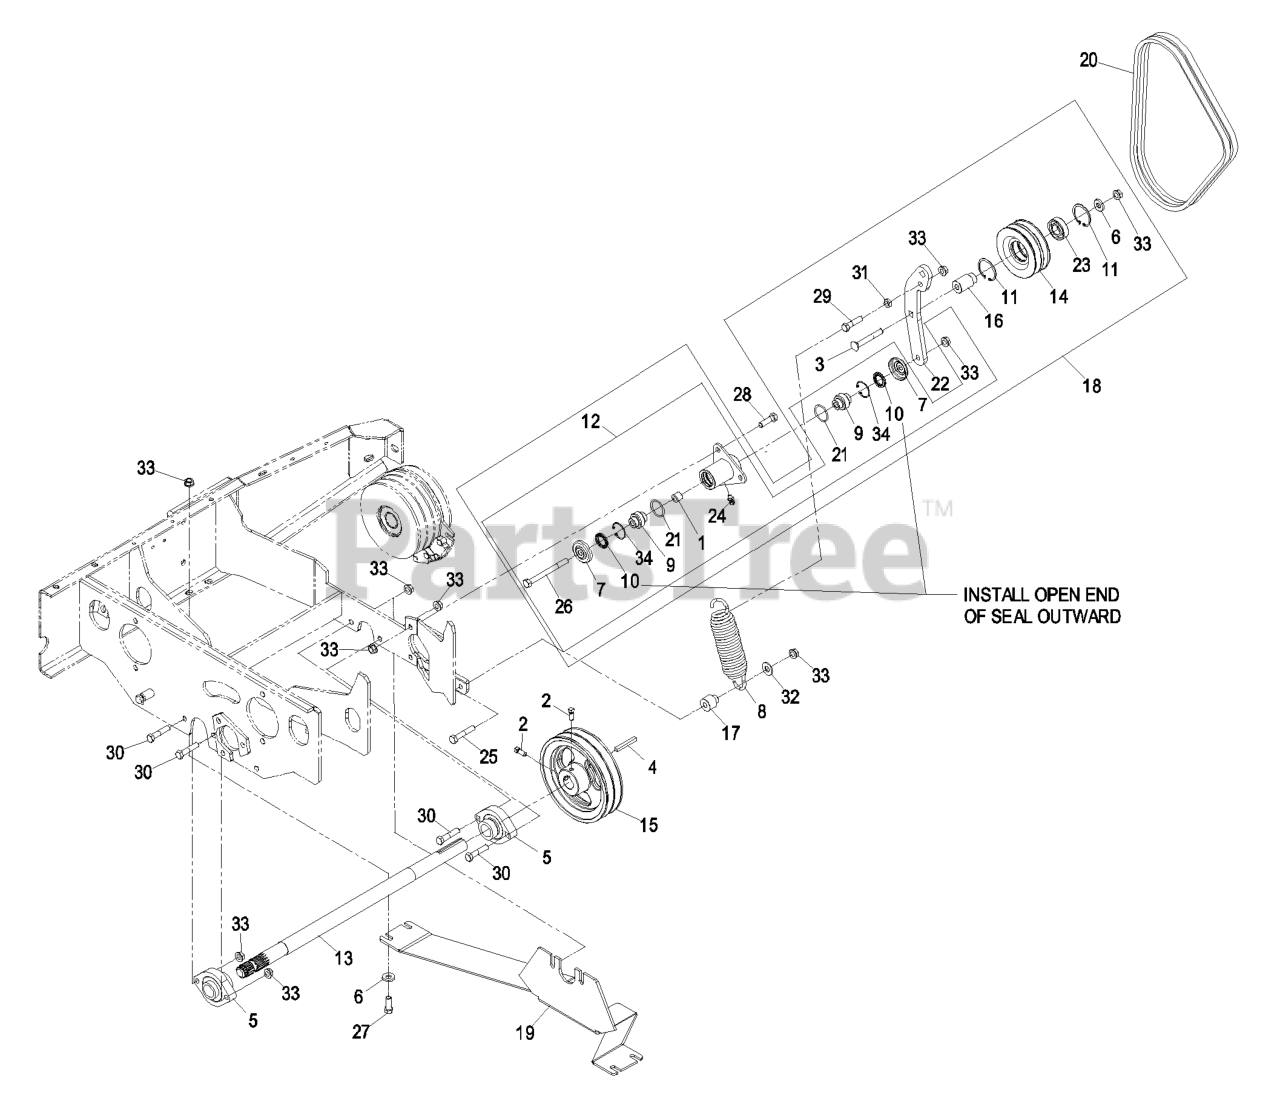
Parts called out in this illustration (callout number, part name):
1	BUSHING-LEVER, LIFT
2	SCREW-SET
3	BOLT,CARRSSN
4	KEY-SQUARE
5	BEARING-FLANGE
6	WASHER-BELLEVILLE
7	GUARD-TOP
9	BEARING-SPHERICAL
10	SEAL-LIP, SINGLE
11	RING-RETAINING
12	KIT,'04 XP PUMP IDLER
13	SHAFT, LINE
15	SHEAVE, 2-A
16	SPACER, IDLER BEARING
17	SPACER, SPRING .75
18	ASM, LINEDRIVE IDLER
19	GUARD, LINEDRIVE
20	BELTS,MATCHED A-COG 39.36
23	BEARING-BALL
24	FITTING-GREASE, 90 DEG
25	SCREW-HH
26	SCREW-HH
27	SCREW-HH
28	SCREW-HH
29	SCREW-HH
30	SCREW-HH
31	NUT-JAM
32	WASHER-FLAT
33	NUT-HHF, WHIZ
34	RING-SNAP
